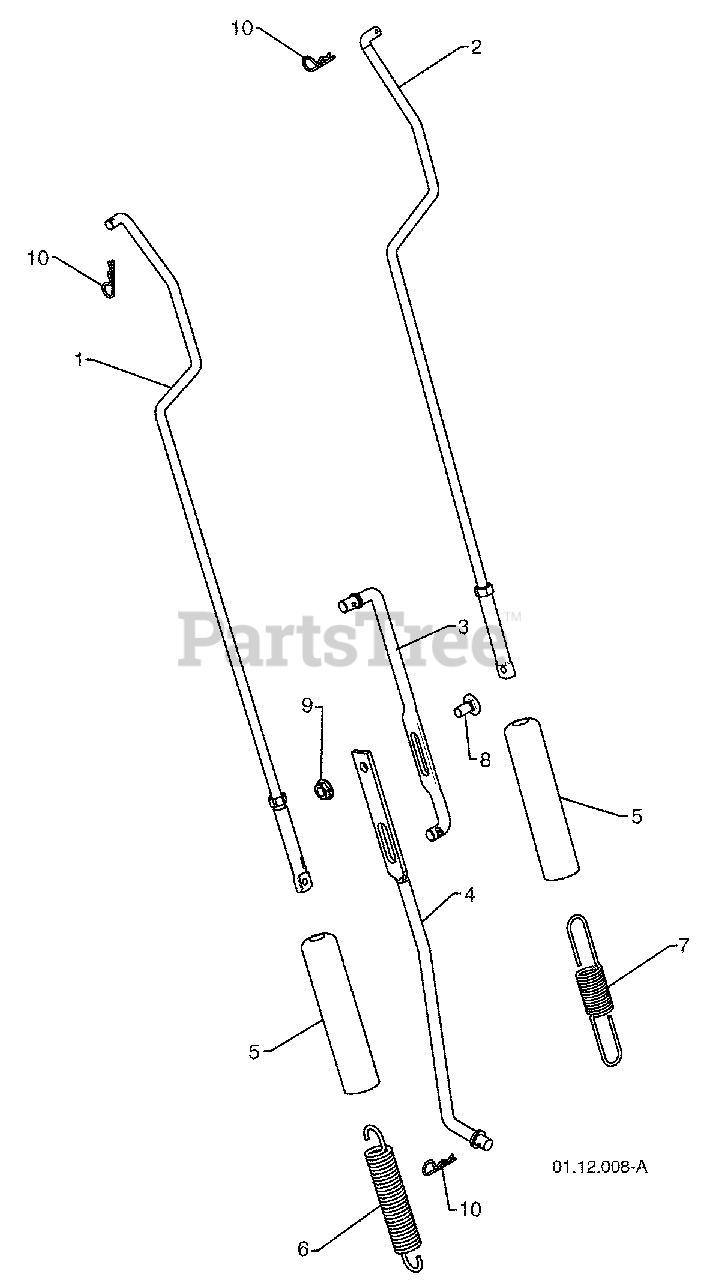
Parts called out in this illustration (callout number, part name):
1	IMPELLER ROD ASSEMBLY
2	TRACTION ROD ASSEMBLY
3	SHIFTER ROD TOP
4	SHIFTER ROD BOTTOM
5	SPRING SLEEVE
6	IMPELLER SPRING
7	TRACTION SPRING
8	CARRIAGE BOLT 5/16-18 X .750
9	NUT 5/16-18
